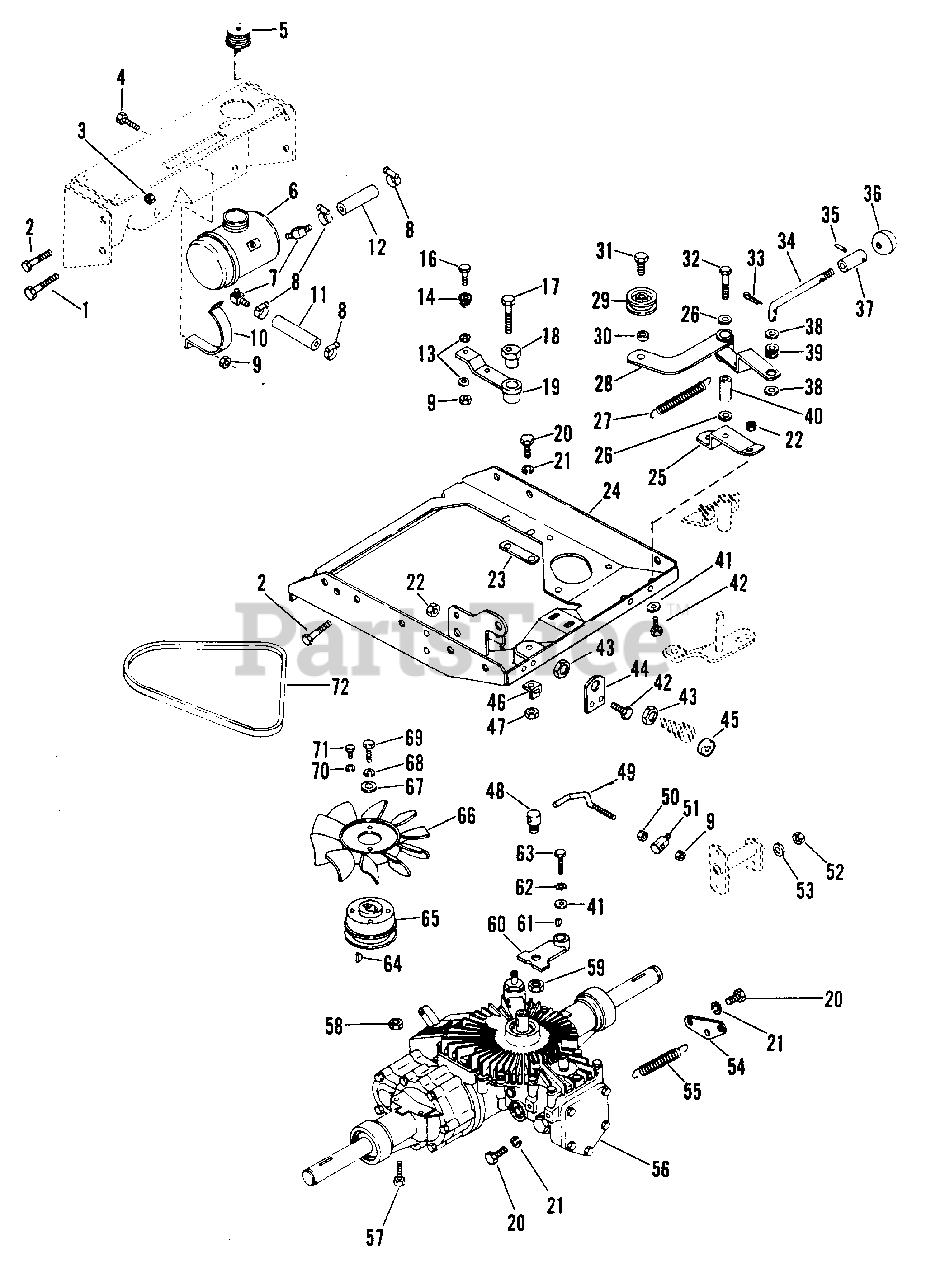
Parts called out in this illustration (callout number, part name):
1	BOLT, HEX 3/8-16X1.00
2	BOLT, HEX 3/8-16X.75
3	NUT, LOCK 3/8-16
4	BOLT, HEX 1/4-20X.875
5	CAP W/DIPSTICK
6	TANK, EXPANSION
7	FITTING, 90 DEGREE
8	CLAMP, HOSE
9	NUT, LOCK 1/4-20
10	STRAP, TANK
11	HOSE
12	HOSE
14	BEARING, BALL
16	BOLT, HEX 1/4-20X1.00
17	BOLT, HEX 5/16-18X2.25
18	ECCENTRIC
19	ARM, DETENT
20	BOLT, HEX 5/16-18X.625
21	WASHER, LOCK 5/16 REG.
22	NUT, LOCK 5/16-18
23	SPACER, TRANSAXLE
24	MOUNT, TRANSAXLE
25	BRACKET, IDLER
26	WASHER, FLAT .313X.875X.065
27	SPRING
28	ARM, CLUTCH W/BUSHING
29	IDLER
30	BUSHING, .37X.62X.25
31	BOLT, HEX 3/8-16X.875
32	BOLT, HEX 5/16-18X2.25
33	PIN, COTTER .125X.75
34	HANDLE, CLUTCH
35	PIN, GROOVE .125X.625
36	KNOB, ADJUSTMENT, CONTROL
37	SPACER, CLUTCH HANDLE
38	WASHER, FLAT .406X.812X.065
39	GROMMET
40	BUSHING, SPACER
41	WASHER, FLAT .312X.734X.065
42	BOLT, HEX 5/16-18X.75
43	NUT, HEX 5/8-32
44	BRACKET, SWITCH
45	BOOT
46	ANCHOR, SPRING
47	NUT, LOCK 5/16-18
48	ADAPTER
49	ROD
50	NUT, HEX 1/4-20
51	PIVOT, ROD
52	NUT, LOCK 5/16-18
53	WASHER, FLAT .312X.734X.065
54	ANCHOR, SPRING
55	SPRING, EXTENSION
56	TRANSMISSION, HYDRO
57	BOLT, HEX 3/8-16X2.75
58	NUT, LOCK 3/8-16
59	NUT, LOCK 1/2-13
60	ARM, SHIFT
61	KEY, WOODRUFF .125X.50 HRD #3
62	WASHER, LOCK 1/4 EXT. TH. TYA
63	BOLT, HEX 1/4-20X1.50
64	KEY, WOODRUFF .187X.625 HRD #61
65	SHEAVE, TRANSMISSION
66	FAN
67	WASHER, FLAT .281X1.000X.063
68	WASHER, FLAT 1/4 REG.
69	BOLT, HEX 1/4-20X.75
70	WASHER, LOCK NO. 10
71	SCREW, MACHINE 10-24X.375 HHD
72	V-BELT
